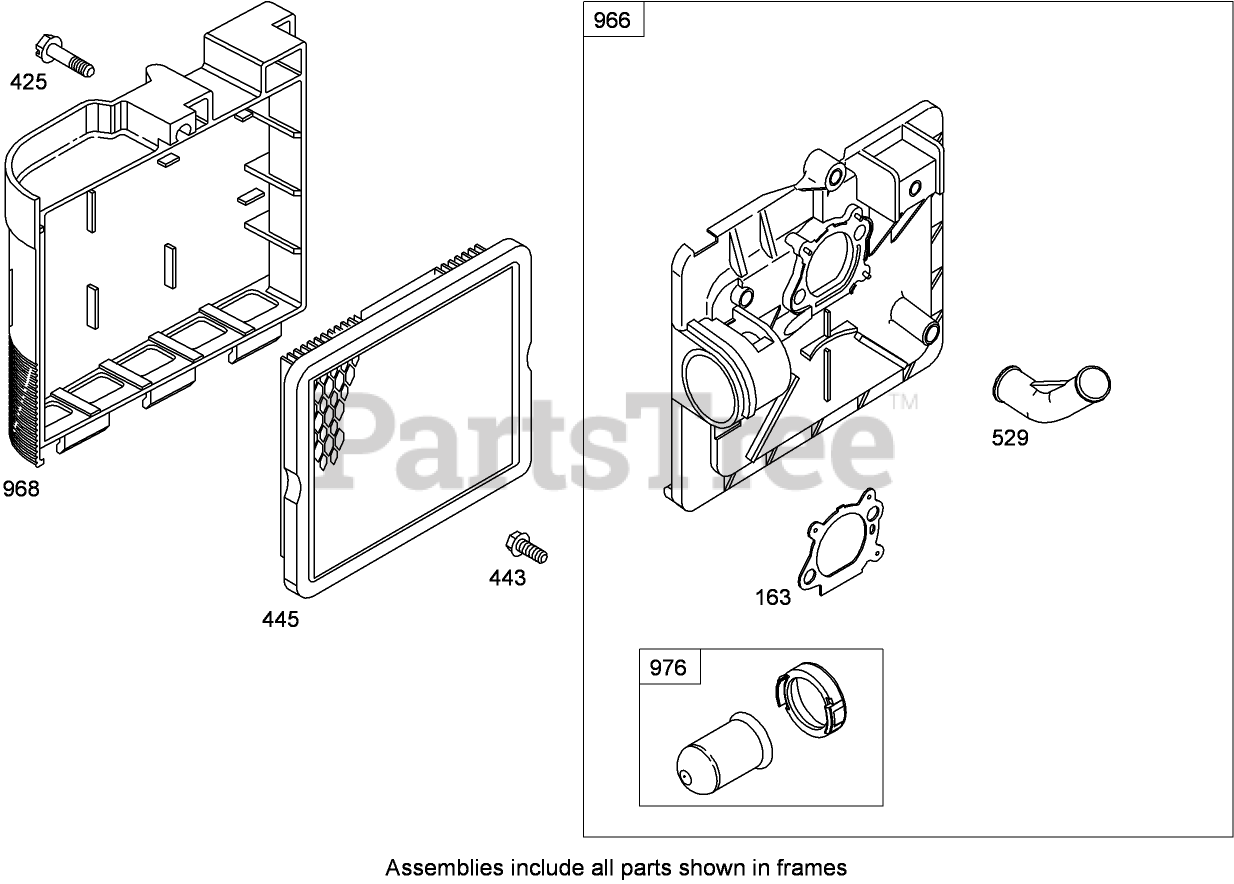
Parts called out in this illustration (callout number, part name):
163	Gasket-Cleaner, Air
425	Screw
443	Screw
445	Filter-Cartridge, Air Cleaner
529	Grommet
966	Pin-Roll
968	Cover-Cleaner, Air
976	Primer-Carburetor
